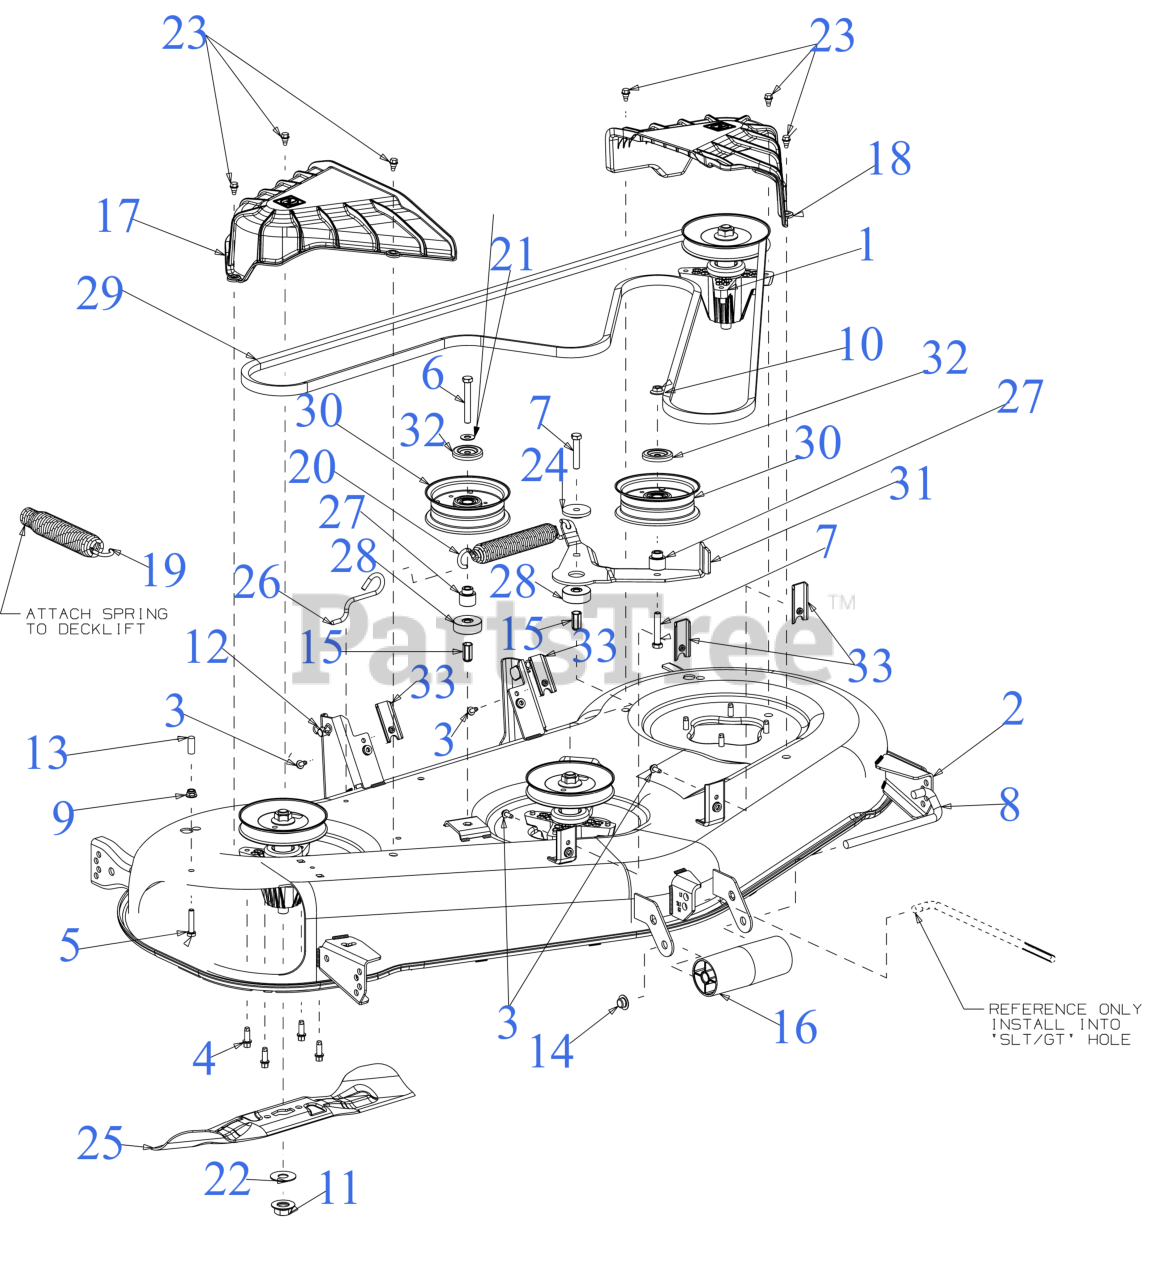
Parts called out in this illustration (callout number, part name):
1	SPINDLE ASSEMBLY
2	54" DECK SHELL
3	SCREW M6-1 x .625
4	SCREW 5/16-18 x .875
5	SCREW 5/16-18 x 1.5 LG
6	SCREW 3/8-16 x 2.75 GR5
7	SCREW 3/8-16 x 2.0 GR 8
8	ROLLER PIN 1/2 x 7.31
9	FLANGE LOCK NUT 5/16-18
10	FLANGE LOCK NUT
11	HEX FLANGE NUT 5/8-18 GR5
12	BOW TIE COTTER PIN
15	NUT RIVET 3/8-16
17	SPINDLE COVER (RH)
18	SPINDLE COVER (LH)
19	LIFT ASSIST SPRING (LARGE)
20	SPRING 1.25" DIA x 8.5" LONG
21	FLAT WASHER .401X.88
22	FLAT WASHER .635X1.585X.062 HDN
23	SHOULDER SCREW 1/4-20 x .50
24	SHOULDER SPACER
25	18.611" BLADE (2IN1) (S SHAPE CENTER HOLE)
25	Cub Cadet 54" HI LIFT BLADE SET (S SHAPE CENTER HOLE) (-05086)
25	Troy-Bilt 54" HI LIFT BLADE SET (S SHAPE CENTER HOLE)
25	18.611" XTREME BLADE (2IN1) (S SHAPE CENTER HOLE)
25	Cub Cadet 54" XTREME BLADE SET (S SHAPE CENTER HOLE) (-05086-X)
25	Troy-Bilt 54" XTREME BLADE SET (S SHAPE CENTER HOLE)
25	18.611" LOW LIFT (S SHAPE CENTER HOLE)
25	Cub Cadet 54" LOW LIFT BLADE SET (S SHAPE CENTER HOLE) (-05086-L)
25	Troy-Bilt 54" LOW LIFT BLADE SET (S SHAPE CENTER HOLE)
26	DECK SPRING HOOK
27	SHOULDER SPACER
28	SPACER .385ID x 1.75OD x .585THK
29	V-BELT B SEC x 139
29	Cub Cadet 54" DECK DRIVE BELT
29	Genuine Factory Parts 54" DECK BELT
30	IDLER PULLEY 4.50" DIA
31	IDLER PIVOT BRACKET
32	IDLER PULLEY CAP
